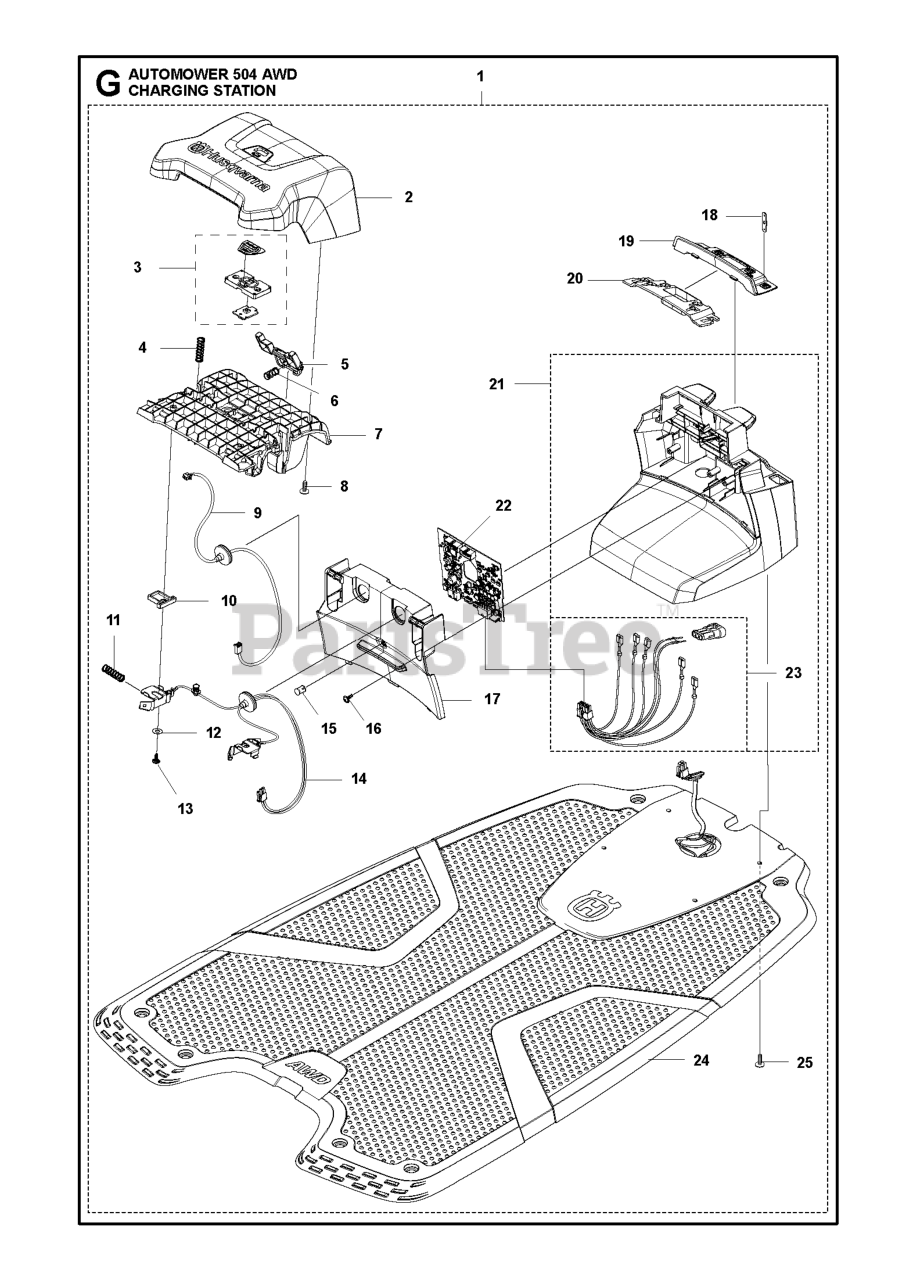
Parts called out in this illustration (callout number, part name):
1	Charging Station
2	CAP CHARGING STATION WITHOUT H
2	CAP CHARGING STATION
3	BUTTON KIT HOME
4	SPRING SPRING CAP
5	BUTTON CHARGING STATION, RELEA
6	SPRING STOP BUTTON
7	FRAME CHARGING STATION
8	SCREW 14MM
9	LOOM HOME BUTTON
10	DISTANCE CHARGING STATION
11	SPRING SPRING CAP
13	SCREW 14MM
14	CABLE ASSY CHARGING CONTACTS
15	LENS DIODE
16	SCREW 14MM
17	LID CHARGING STATION 330, TWO
17	LID CHARGING STATION 320, ONE
18	TERMINAL TERMINAL CHARGING STA
19	PANEL CHARGING STATION 340, TH
20	HOLDER CHARGING STATION
21	HOUSING ASSY CHARGING STATION
22	Circuits
23	CABLE KIT GENERATOR BOARD
24	Bases
25	SCREW 14MM
